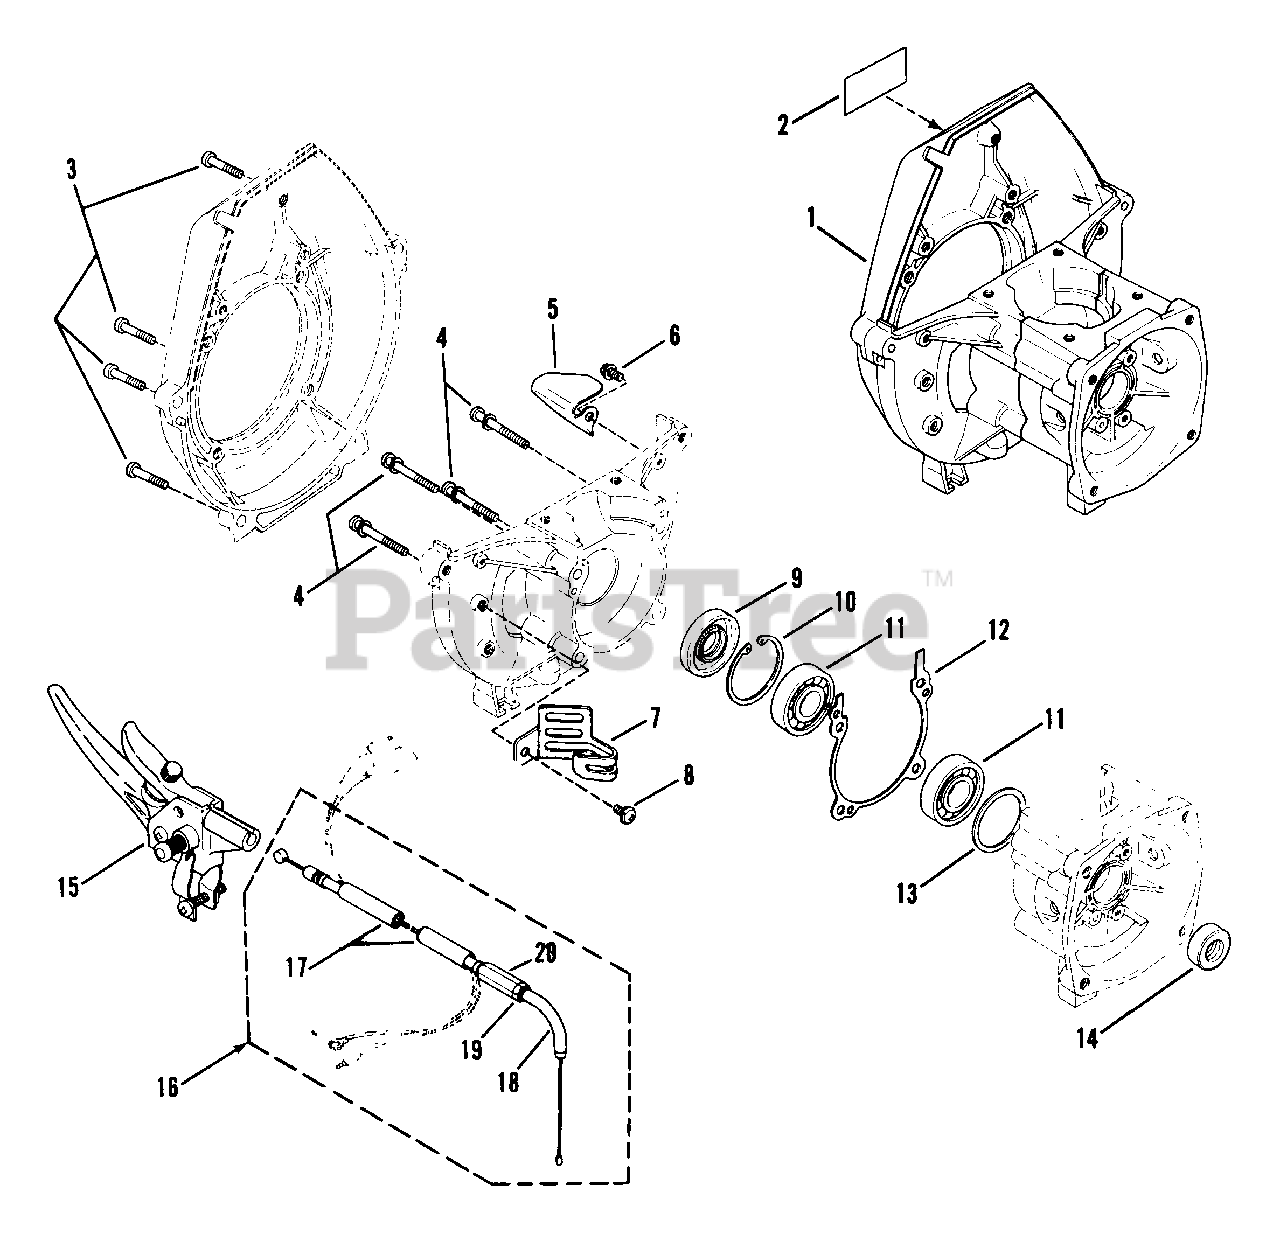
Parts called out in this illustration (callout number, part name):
1	CRANK CASE ASSM'Y.
2	DECAL, Serial Number
9	SEAL, Oil
10	SNAP-RING
11	BEARING
12	GASKET, Crankcase
13	SHIM (Set of 3)
14	SEAL, Oil
15	LEVER, Throttle
16	CABLE, Throttle Assm'y.
17	CABLE & JACKET
19	NUT, Lock
20	NUT, Adjusting
